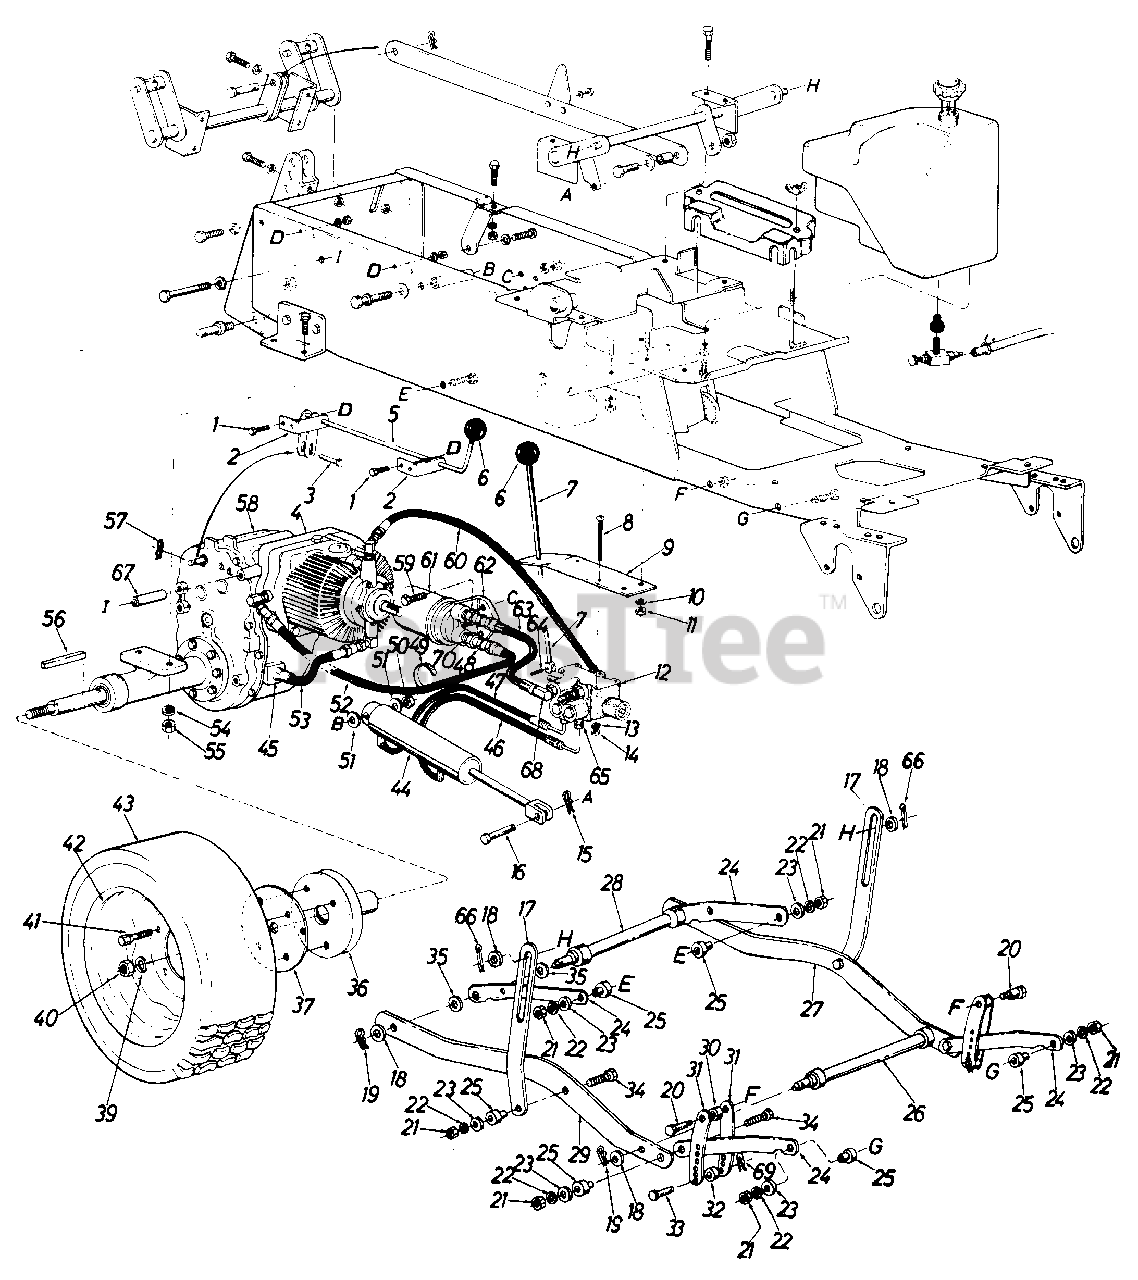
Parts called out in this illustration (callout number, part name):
1	Hex Scr. 1/4-20 x .75" Lg.*
2	Hi-Lo Speed Control Brkt.
3	Clevis Pin 1/4" Dia.
4	Hydrostatic Pump Comp.
5	Hi-Lo Control Handle Ass'y.
6	Ball Knob
7	Cylinder Control Handle Ass'y.
8	Truss Mach. Scr. 1/4-20 x 3.00" Lg.*
11	Hex Nut 5/16-18 Thd.*
12	Valve Ass'y. Comp.
13	L-Wash. 1/4" Scr.*
14	Hex Nut 1/4-20 Thd.*
15	Hairpin Cotter 1/2" Dia.
16	Clevis Pin 1/2" Dia.
19	Hairpin Cotter
20	Shld. Scr. .498 Dia. x .66
21	Hex Nut 3/8-24 Thd.*
22	L-Wash. 3/8" Scr. H.D.
23	Fl-Wash. .38 I.D. x 1.00" O.D.
24	Lift Arm
25	Shoulder Spacer
26	Cross Shaft Ass'y. Front
31	Index Brkt.
32	Spacer.38" I.D. x 1.00" O.D. x .320
33	Clevis Pin 3/8" Dia.
34	Hex Scr. 3/8-24 x 1.50" Lg. Grade 5
35	Fl-Wash. .62" I.D. x 1.25" O.D. x .020
39	L-Wash. 3/4" Scr.*
40	Hex Ins. L-Nut 3/4-16 Thd.
41	Wheel Lug Bolt 1/2-20 x 1.50" Lg.
44	Hydraulic Cylinder
45	7/8-14 UNF-2A Thd. 5/8 Tube Fitting
46	Valve to Cylinder Hose 20" Lg .
47	Valve to Cylinder Hose 20" Lg.
48	Bushing Reducer 1/2-14 NPTF to 3/8-18 NPTF
49	Cable Tie
50	Hex Jam Nut 1/2-20 Thd.
51	Fl-Wash. .50" I.D. x 1.25 O.D.
52	Filter Return Hose 24" Lg.
53	Pu mp Tu be Ass'y.
54	L-Wash. 3/8" Scr.*
55	Hex Nut 3/8-16 Thd.*
56	Sq Key 1/4 X 1/4 X 2.00*
57	Hairpin Cotter 1/4" Dia.
58	Peerless Transaxle
59	Hex Scr. 5/16-18 x 1.25"*
60	Pump to Valve Hose
61	Fram Filter Ass'y. PH-16
62	Filter Base
63	Valve to Filter Hose 8.38" Lg.
64	Spring Pin Spiral 1/8" Dia. x.81" Lg.
65	Flare Adapter
66	Cotter Pin 1/8" Dia. x 1.00" Lg.*
67	Spacer
68	Adapter 9/16-18 to 9/16-18
69	Hairpin Cotter
70	Reducer 1/2-3/8 NPT
